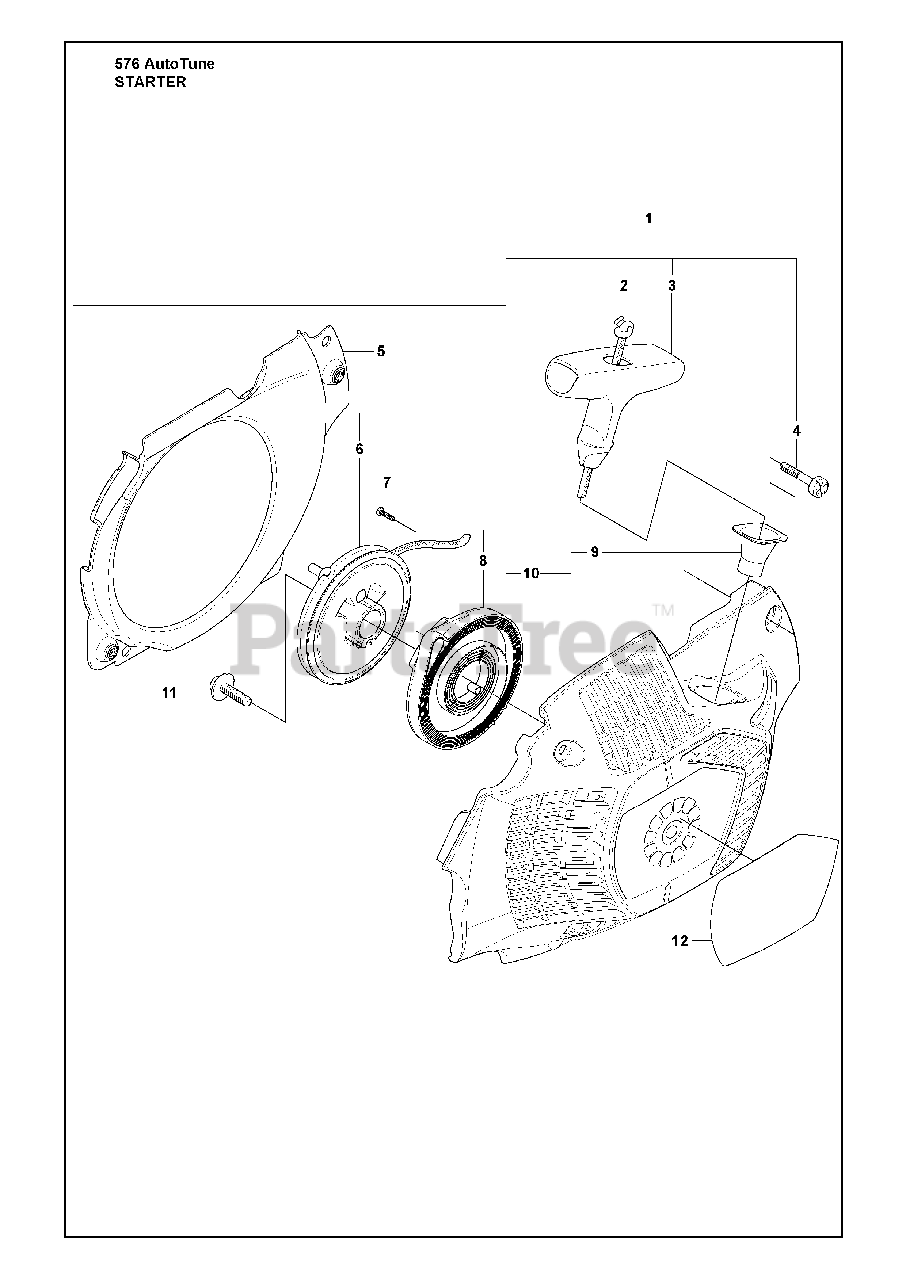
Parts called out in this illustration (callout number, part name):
1	STARTER ASSY
2	STARTER ROPE
6	STARTER PULLEY
8	RP SPRING
10	STARTER HOUSING
12	LABEL
12	LABEL (576XPG AUTO TUNE)
